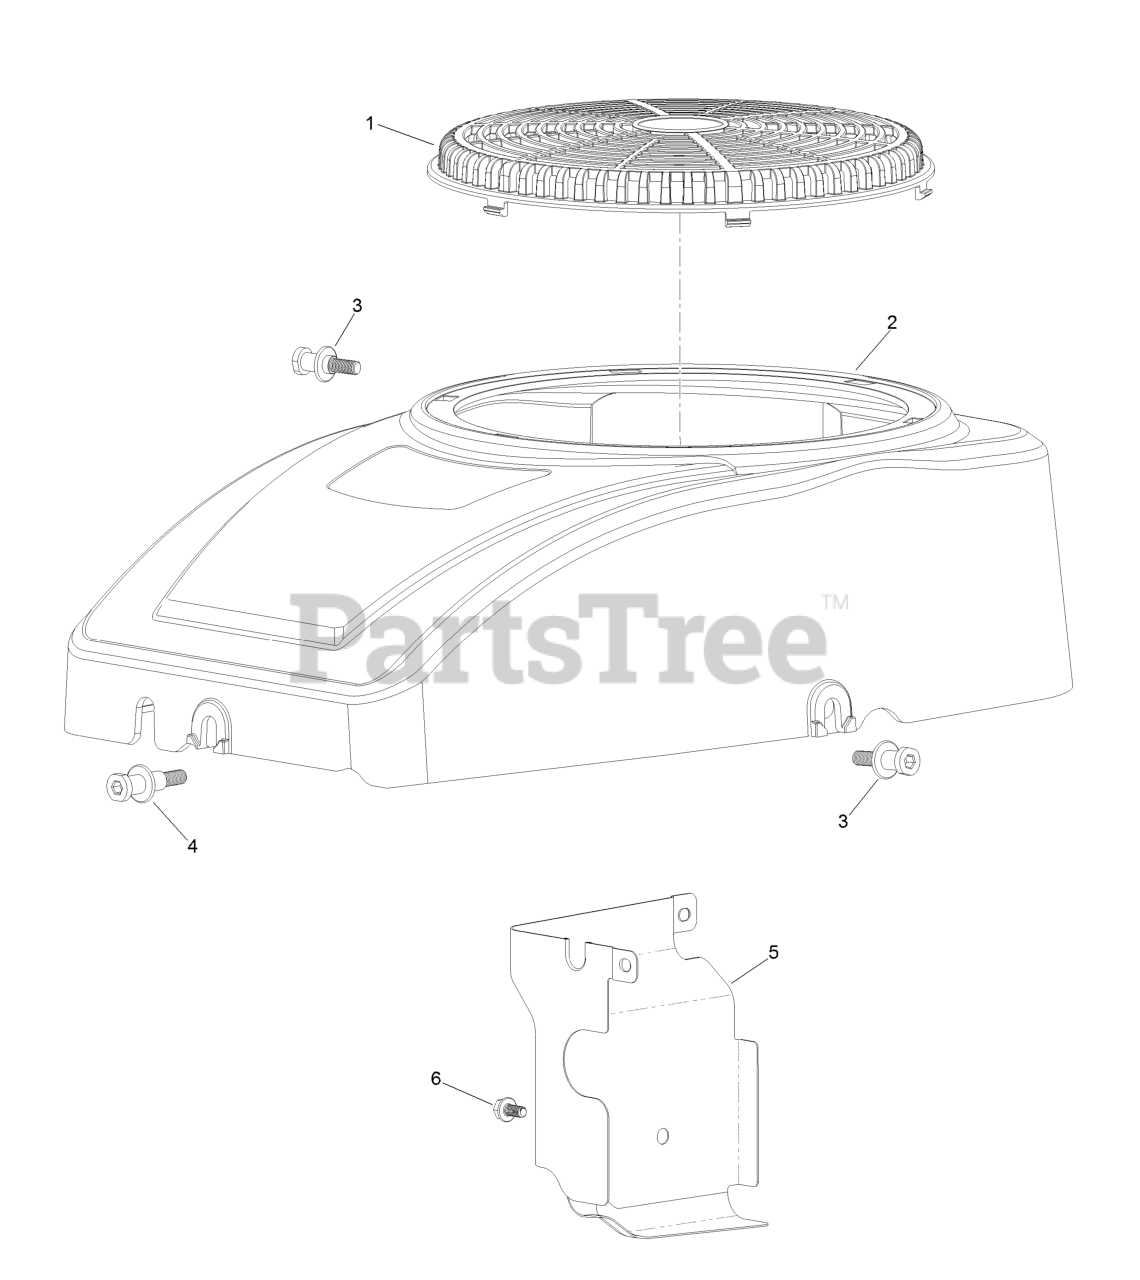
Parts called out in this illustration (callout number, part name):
1	SCREEN-STATIONARY
2	SHROUD-FAN
3	SCREW-SHOULDER, HH
4	SCREW-SHOULDER, HH
6	SCREW-HHF
